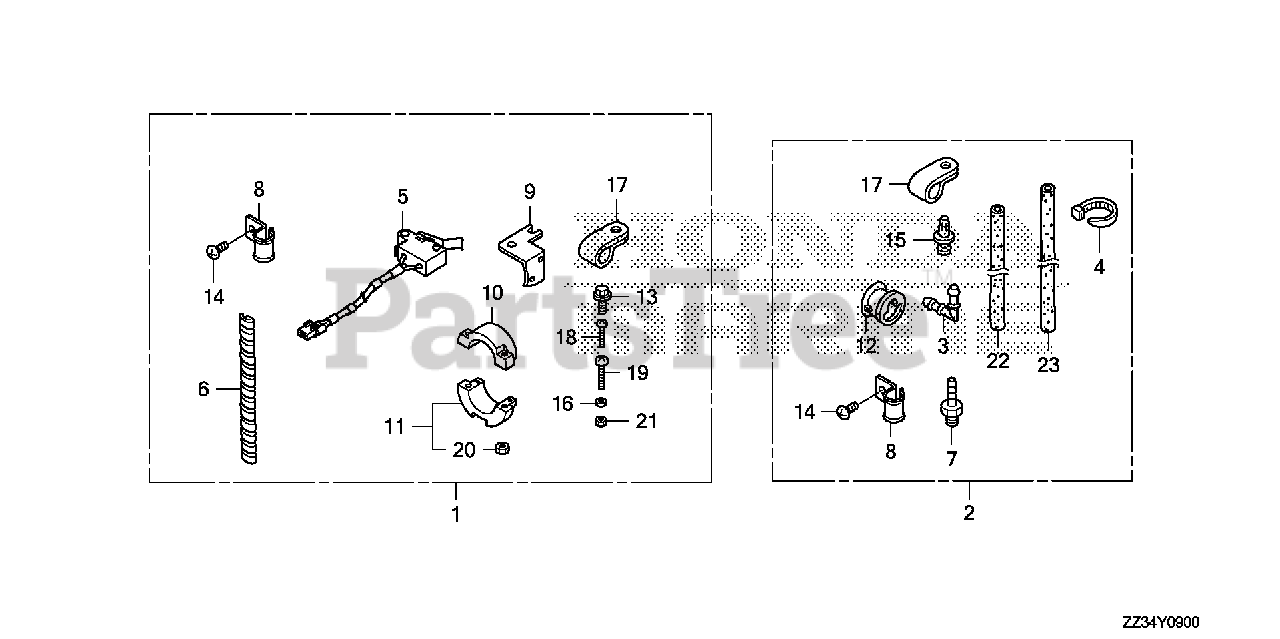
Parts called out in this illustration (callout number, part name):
1	LIMIT KIT, TILT
2	TUBE KIT, SPEED SENSOR
3	JOINT A, BREATHER
4	BAND, WIRE
5	SWITCH ASSY., TILT LIMIT
6	TUBE, SPIRAL
7	NIPPLE, SENSOR
8	CLAMP, TUBE
9	BRACKET, TILT LIMIT SENSOR
10	CAM A, TILT LIMIT ANGLE
11	CAM B, TILT LIMIT ANGLE
12	BUSH, MOTOR CODE
13	BOLT, FLANGE (6X12)
14	SCREW, PAN (6X8)
15	SCREW, RIVET (5X10)
16	WASHER, PLAIN (4MM)
17	CLIP (14MM)
18	SCREW, PAN (4X14)
19	SCREW, PAN (5X20)
20	NUT, HEX. (5MM)
21	NUT, HEX. (4MM)
22	BULK HOSE, VACUUM (5X3000) (5X530)
23	BULK HOSE, VACUUM (5X3000) (5X950)
